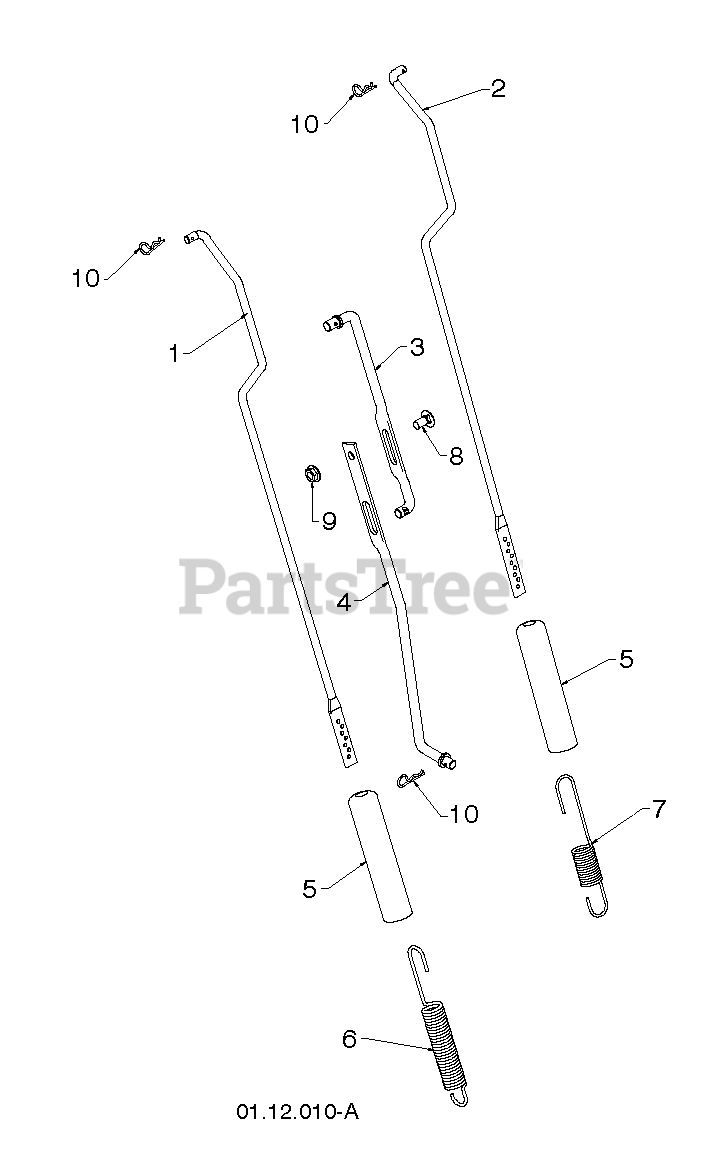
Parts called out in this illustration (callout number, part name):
1	ROD.IMPELLER.CONTROL.SNOW
2	ROD.TRACTION.CONTROL.SNOW
3	ROD, UPPER SPEED CONTROL
4	ROD, LOWER SPEED CONTROL
5	SLEEVE, SPRING
6	SPRING.CONTROL.ROD.SNOW
7	SPRING.TRACTION.ROD.SNOW
8	BOLT
9	NUT.FLANGE.5/16
10	SPRING RETAINER
